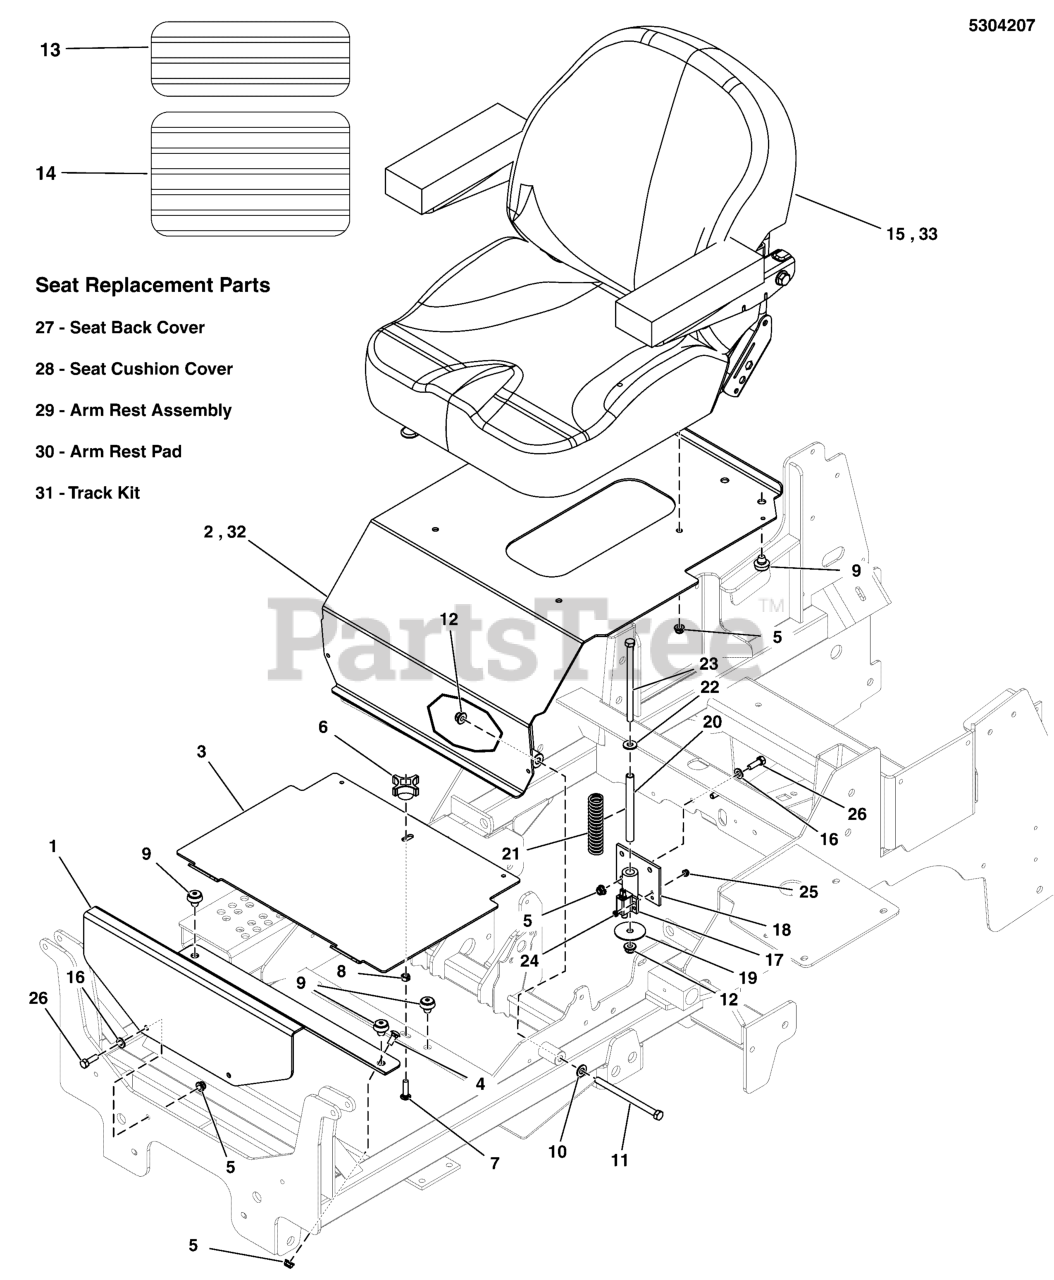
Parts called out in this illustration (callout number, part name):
1	PLATE, FRONT FLOOR, IS2600Z - RED
2	ASSM, SEAT PLATE W/ DECALS, IS2600Z-DOM
3	PLATE, FLOOR, REMOVABLE, IS700 - RED
4	BOLT, 5/16-18 X 3/4, CARRIAGE, GD5, CZ
5	NUT, 5/16-18 HEX NYLOCK FLANGE NUT
6	KNOB-INT THR .312-18 4-ARM 2.12WD 1.06LG
7	BOLT,5/16-18X1.500,CARRIAGE,SQ,GR5,ZC/CL
8	NUT, 5/16-1/8, HEX, CNTR LK, ZINC PHOS/OIL
9	MNT, VBRTN, RBBR
10	WASHER, 3/8 SAE
11	BOLT, 3/8-16 X 5-1/2" GD5 CZ
12	NUT, 3/8 - 16 HEX NYLOCK FLANGE
13	SAFETY WALK, FLOOR PLATE, S50X, 10X17.13
14	SAFETY WALK, FLOOR REST, 16.00 X 6.00
15	SEAT, CI3, SEAT'S INC. 2016
16	WASHER, 5/16" SAE
17	SWITCH, PLUNGER, N.C.
18	WELD, SEAT SWITCH
19	WASHER, .39 X 2.00 X X .14
20	SPACER, .38 X .50 X 5.06, CZ
21	SPRING, .688 ID X .130 WIRE DIA 4.25
22	WASHER, 3/8" USS
23	BOLT, 3/8-16 X 6" GD5 CZ
24	SCREW, #10-24 X 3/4" ROUND PHILLIPS
25	NUT, Hex, Nylon Lock, #10-24
26	BOLT, 5/16-18 X 1" GRD5 YZ
27	BACK, COVER, CI3 SEAT
28	CUSHION COVER, CI3 SEAT
29	LEFT AND RIGHT HAND ARM ASSEMBLIES, CI3 SEAT
30	ARM PAD, C13 SEAT
31	TRACK KIT, CI3 SEAT
32	ASSM, SEAT PLATE W/DECALS, IS2600-CE
33	SEAT, C13, SEAT'SINC, 2016, W/SWITCH
